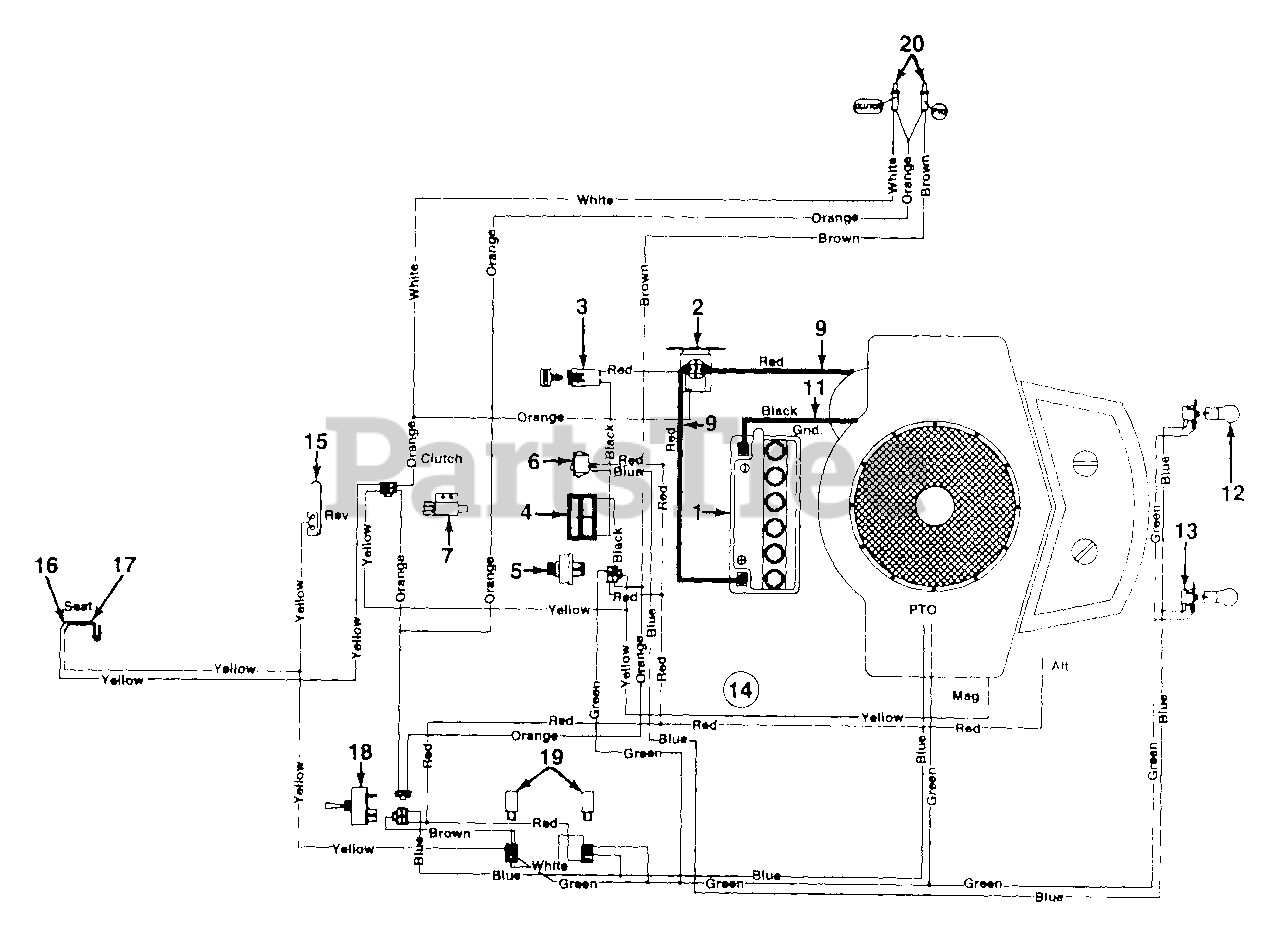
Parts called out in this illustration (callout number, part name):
1	Battery (275 Cold Crank Amps)
2	Solenoid
3	Fuse 20 Amp
4	Ammeter
5	Ignition Switch
6	Light Switch
7	Safety Switch (Clutch)
9	Electric Wire 14" Lg.
11	Ground Wire 7.5" Lg.
12	Lamp
13	Socket
14	Wire Harness
15	Spring Switch (Reverse)
16	Spring Switch (Seat)
17	Spring Switch (Seat)
18	Switch (Clutch)
19	Relay
20	Bulb
